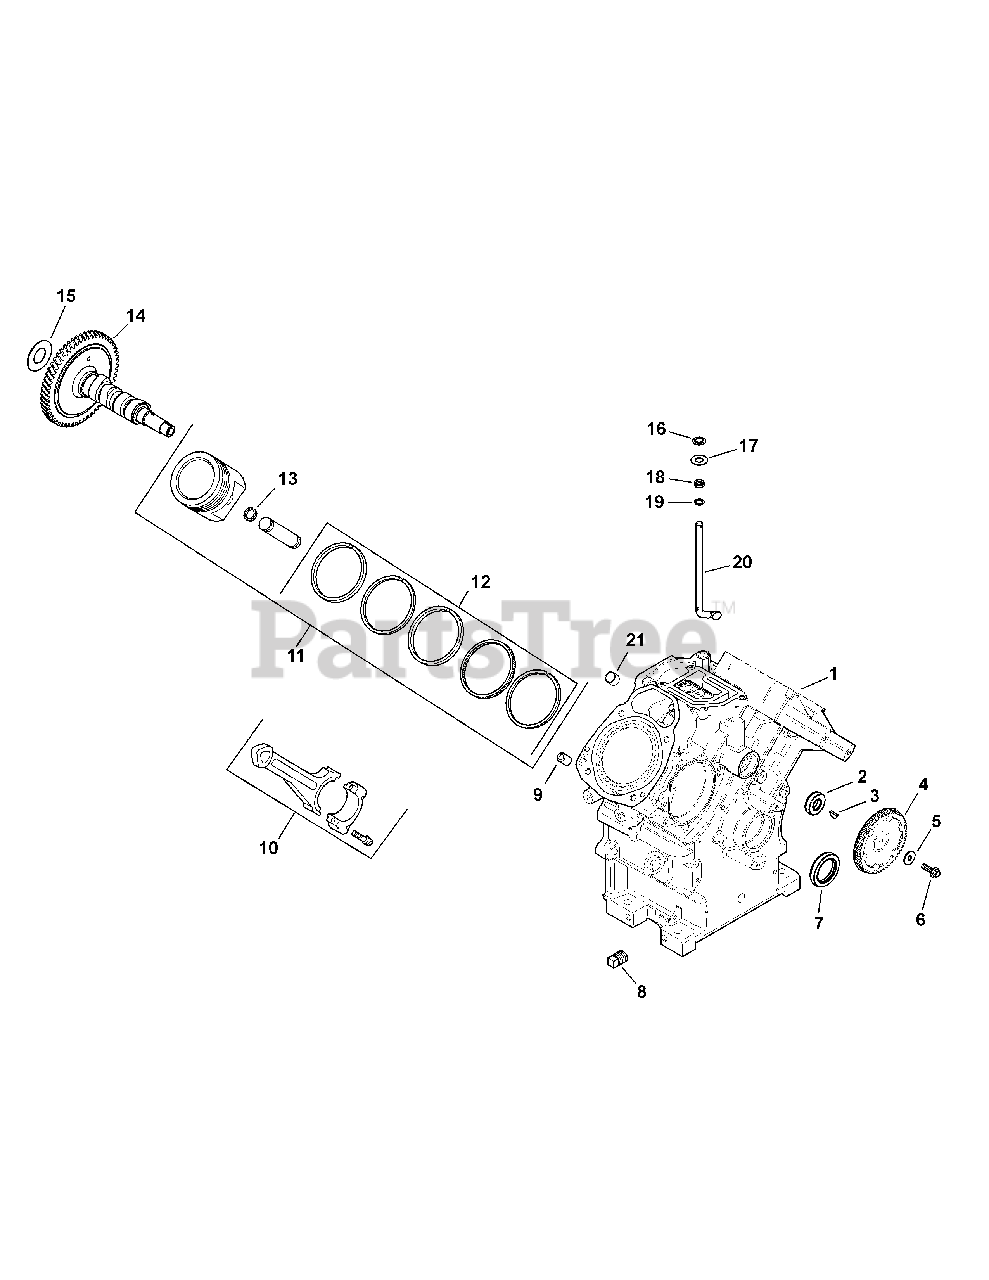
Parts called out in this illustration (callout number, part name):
1	Crankcase
2	SEAL, CAMSHAFT
3	KEY, 3/32" X 3/8"
4	SPROCKET, CAMSHAFT
5	WASHER, FLAT 1/4"
6	SCREW, FLG M6x1.0x20
7	SEAL, OIL (HELIX LIP)
8	PLUG, SQ HD PIPE 3/8"
9	PIN, LOCATING
10	CONNECTING ROD (STD)
10	CONNECTING ROD (.25)
11	KIT, PISTON W/RING SET (STD)
11	KIT, PISTON W/RING SET (.08)
12	RING SET (STD)
12	RING SET (.08)
13	RETAINER, PISTON PIN
14	KIT, CAMSHAFT-EFI
15	SHIM, CAMSHAFT (WHITE .028")
15	SHIM, CAMSHAFT (BLUE .03")
15	SHIM, CAMSHAFT (RED .032")
15	SHIM, CAMSHAFT (YELLOW .034")
15	SHIM, CAMSHAFT (GREEN .036")
15	SHIM, CAMSHAFT (GRAY .038")
15	SHIM, CAMSHAFT (BLACK .04")
16	RETAINER, RING
17	WASHER, FLAT 9 MM
18	SEAL, GOVERNOR CROSS SHAFT
19	WASHER, FLAT 11/32"
20	SHAFT, GOVERNOR CROSS
